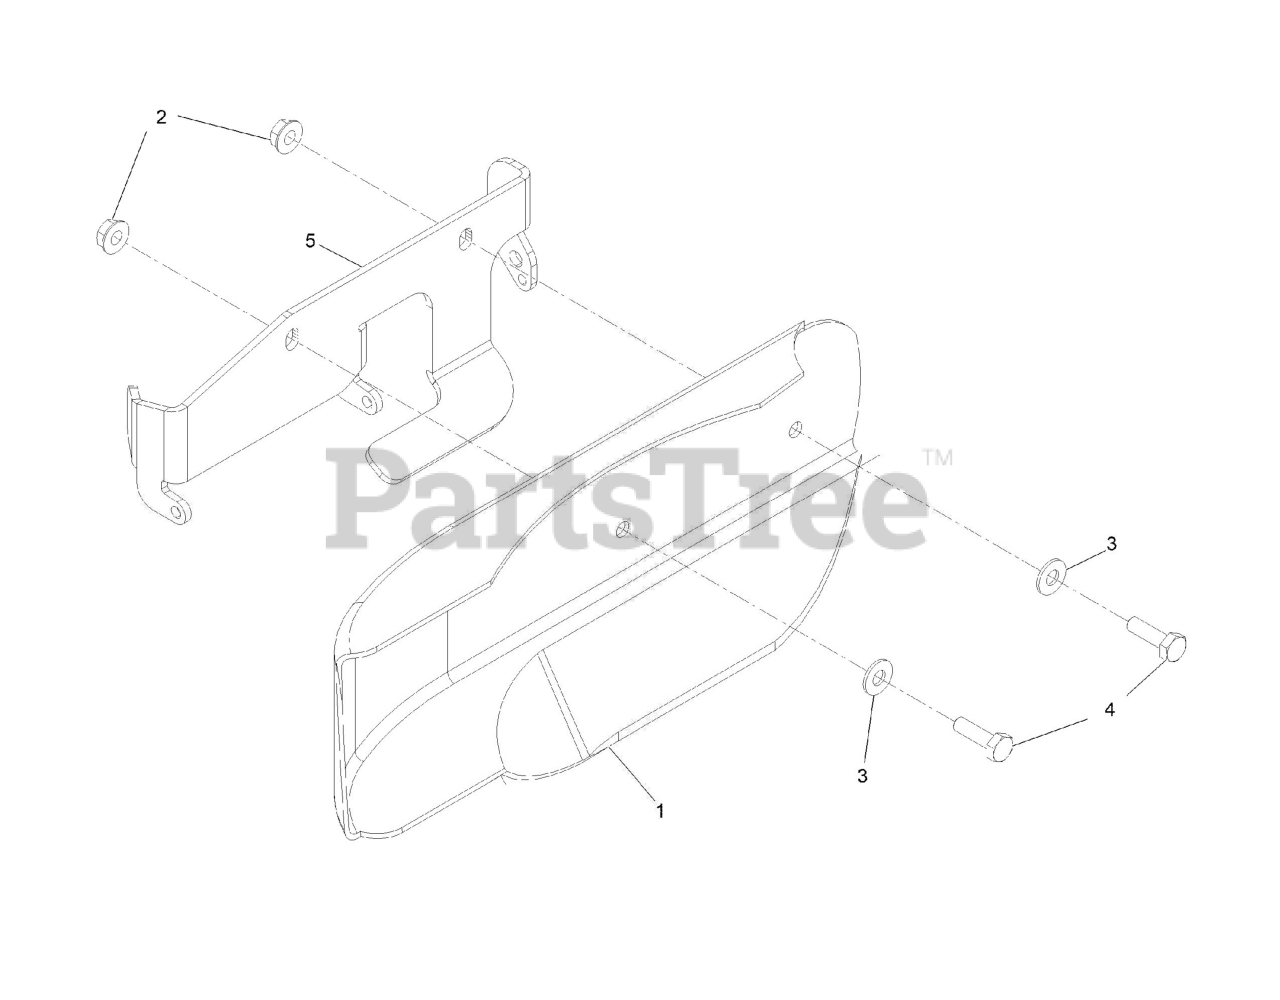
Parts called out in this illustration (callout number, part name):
1	Screw-HH 1/4-20 X 7/8 SS
2	BRACKET-DEFLECTOR, SIDE
3	WASHER-FLAT
4	SCREW-HH
